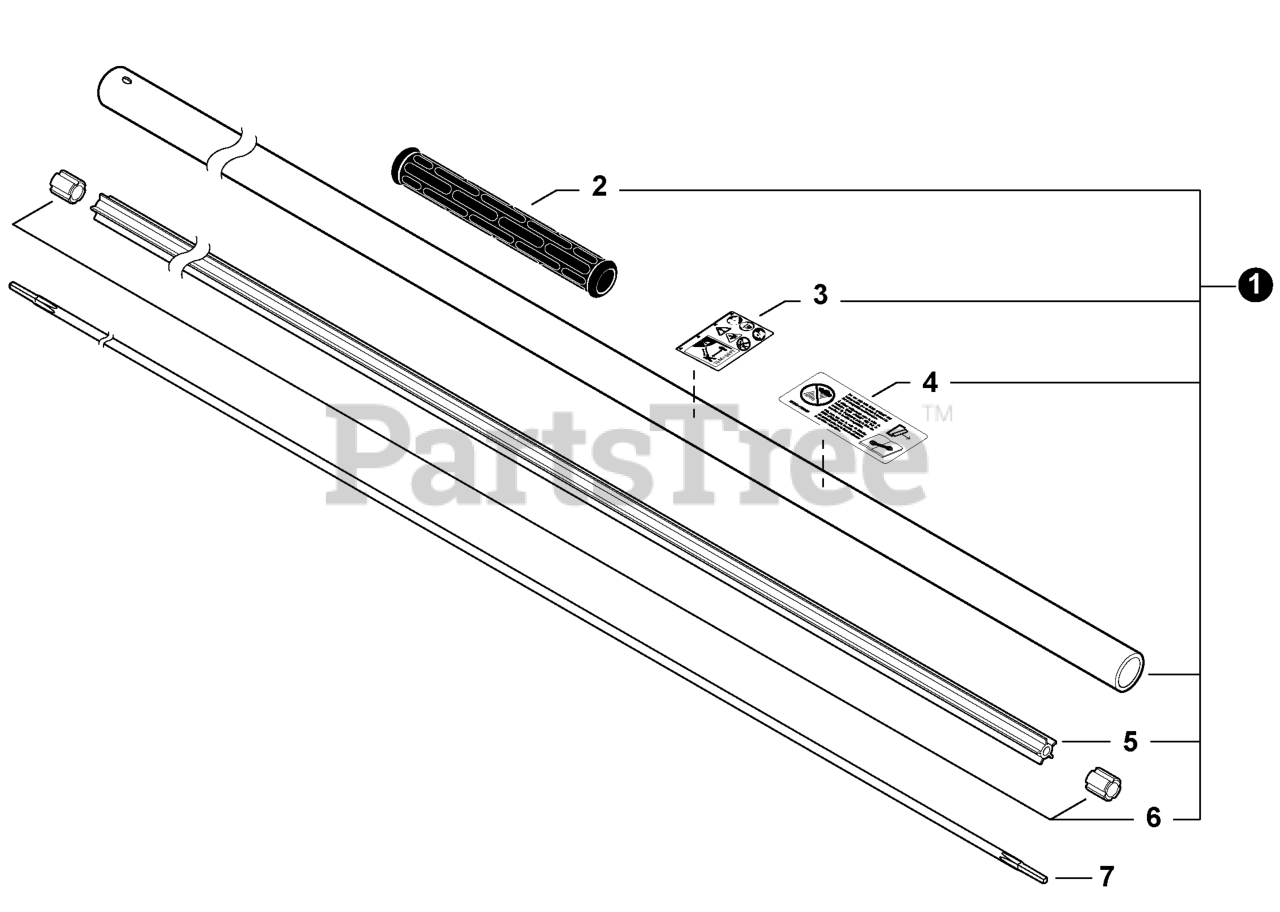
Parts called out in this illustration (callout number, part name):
1	MAIN PIPE ASSY
2	GRIP, FRONT
3	LABEL - CAUTION ISO
4	LABEL - CAUTION - UL
5	STOPPER
6	LINER - FLEXIBLE
7	DRIVESHAFT - FLEXIBLE
